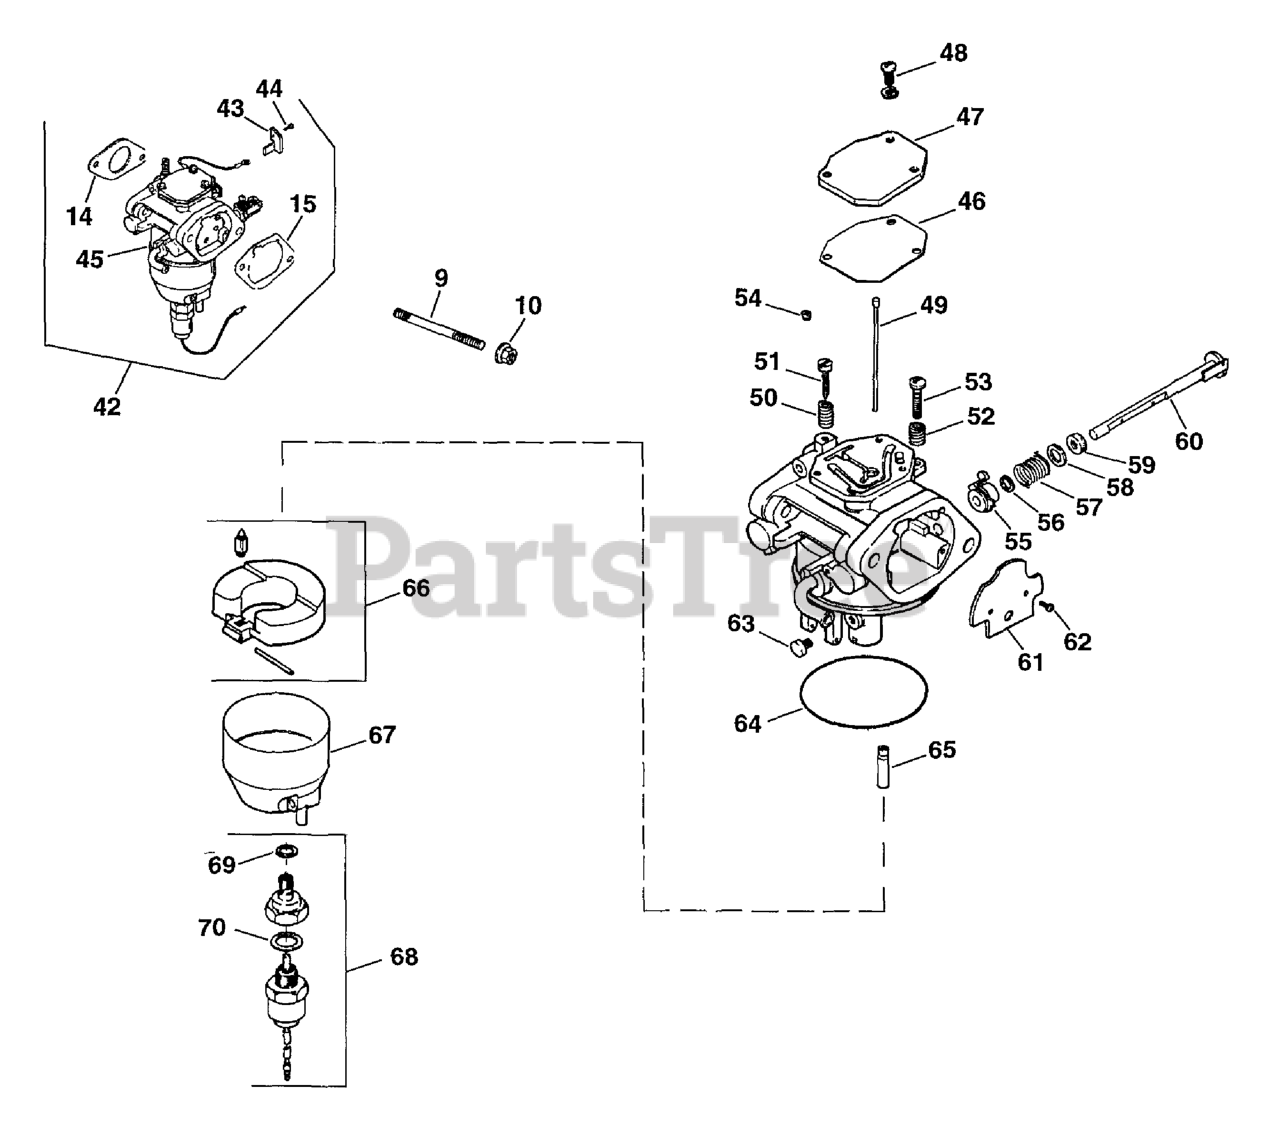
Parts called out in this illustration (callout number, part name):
9	Stud, M6x1.0x128
10	NUT - USE M-641060
14	GASKET, CARBURETOR
15	GASKET, AIR CLEANER BASE
45	Carburetor assembly
46	KIT - USE 24 757 20
47	COVER, PASSAGE - DISCONTINUED
48	SCREW DISCONTINUED
49	JET, SLOW - DISCONTINUED
50	KIT - USE 24 757 18
51	SCREW, IDLE ADJUST - USE 24 757 18
52	SPRING, THROTTLE - DISC
53	KIT - USE 24 757 18
54	JET, AIR BLEED - DISC.
56	RING, CHOKE LEVER-USE 24 757 19-S
58	COLLAR, CHOKE-USE 24 757 19-S
59	WASHER-USE 24 757 19-S
60	SHAFT, CHOKE-USE 24 757 19-S
61	PLATE - USE 24 146 13
62	SCREW - DISCONTINUED
63	JET, MAIN - DISCONTINUED
64	KIT - USE 24 757 20
65	NOZZLE DISCONTINUED
66	KIT - USE 24 757 18
67	CHAMBER, FLOAT
68	KIT - USE 24 757 22
69	DISC. SEE PARTS BULLETIN
70	KIT - USE 24 755 15
